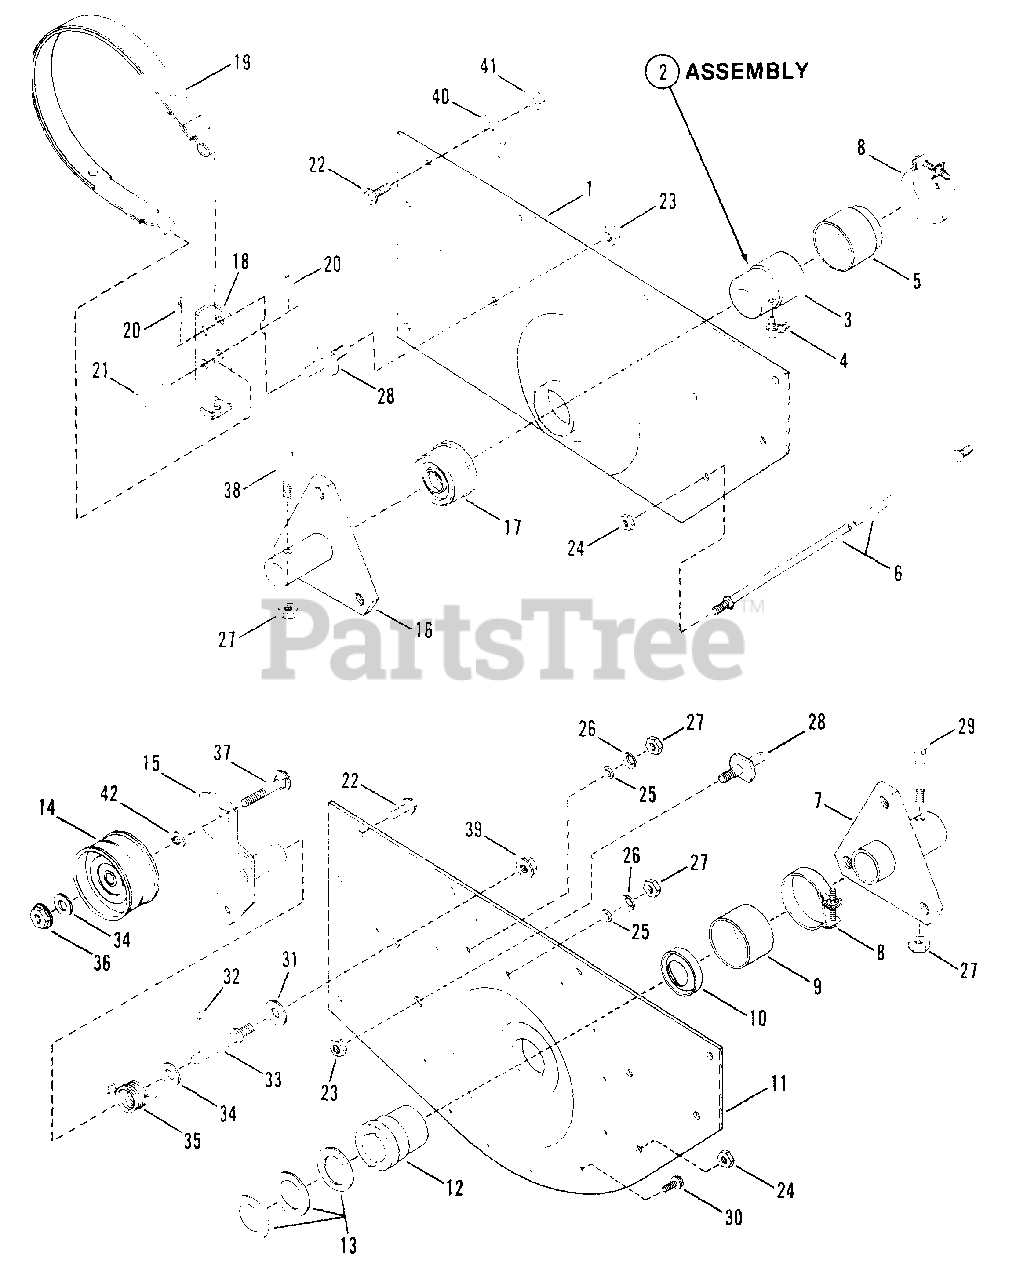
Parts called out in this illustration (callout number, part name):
1	FRAME SIDE, Right Hand
2	ASSEMBLY, Axle Bearing
3	BEARING, Axle
4	FITTING, Lube
5	CAP
6	ROD, Tie
7	HUB, Rear Wheel, Left Hand
8	CLAMP, 1-7/8"
9	CAP, Dust
10	SEAL, 1-1/8"
11	FRAME SIDE, Left Hand
12	BEARING, Axle
13	WASHER, Thrust
14	PULLEY, Idler
15	IDLER ARM
16	HUB, Rear Wheel, Right Hand
17	CAP, Seal L.H. 3/4"
18	ARM, Brake
19	BAND, Brake
20	COTTER-PIN, 1/16 x 1/2"
21	PIN, Clevis
22	SCREW, 5/16-18 x 3/4" Self-Tapping
23	LOCKNUT, 3/8-24 Hex
24	NUT, 5/16-24 Hex
25	O-RING, 5/16"
26	WASHER, Belleville
27	NUT, 5/16-24 Hex Lock, GR C
28	STUD, Brake
29	BOLT, 5/16-24 x 2" Tapered, Left Hand
30	SCREW, 1/4-20 x 1/2" H.W.H. Self-Tapping
31	WASHER, 3/8" Flat
32	COTTER-PIN, 3/32 x 1/2"
33	STUD, Idler
34	WASHER
35	SPRING, Idler Return
36	LOCKNUT, 3/8-16 Hex Flange
37	BOLT, 3/8-16 x 1-1/2" Short Neck Carriage
38	BOLT, 5/16-24 x 1-5/8" Tapered, Right Hand
39	LOCKNUT, 3/8-24 Hex Flange
40	CLIP, Harness
41	NUT, 5/16-18 Hex Center Lock
42	RETAINER, Bolt, 3/8"
